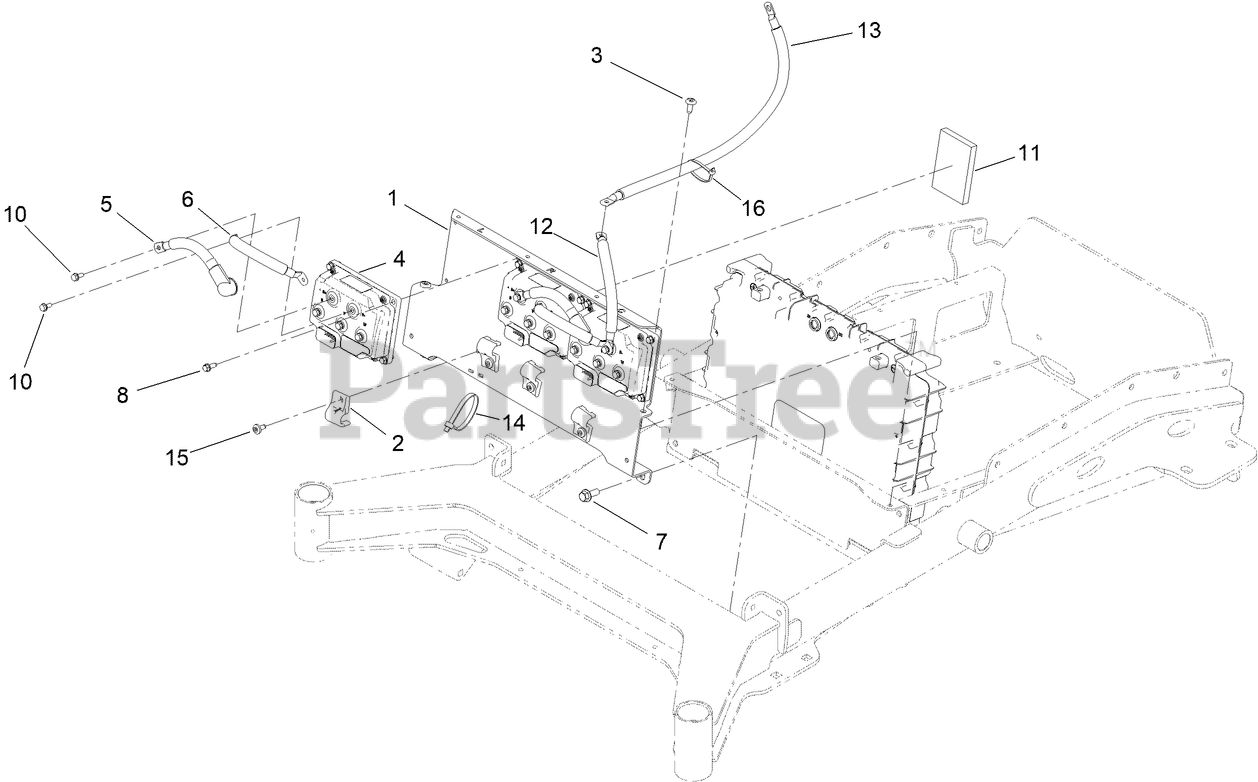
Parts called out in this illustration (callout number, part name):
1	PLATE-MOTOR CONTROLLER MNT
2	MOUNT-CABLE
4	INV/CTRLR-48V
5	CABLE-BATTERY, RD ASM
6	CABLE-BATTERY, BK ASM
7	SCREW-HHF
8	SCREW-HWH, THREAD ROLL
10	SCREW-SEMS
11	PAD-FOAM
12	CABLE-BATTERY, BK ASM
13	CABLE-BATTERY, BK ASM
14	TIE-CABLE
15	SCREW-SHOULDER
16	TIE-CABLE
